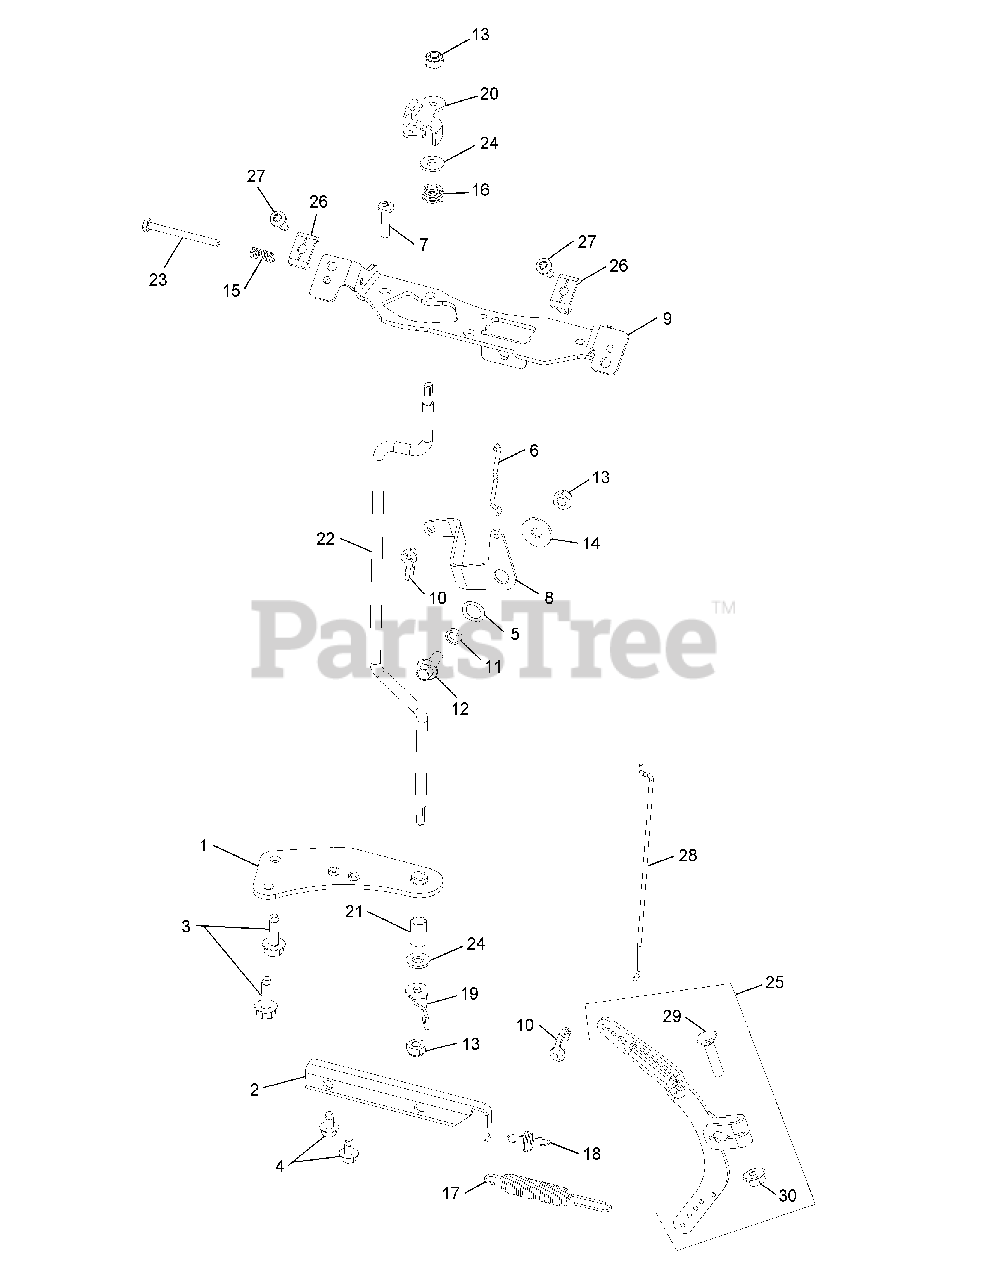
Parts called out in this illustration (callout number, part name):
1	Throttle Shaft Bracket
2	Governed Idle Bracket
3	Thread Forming Screw
4	Thread Forming Screw
5	Spring Washer, 3/8
6	Choke Linkage
7	Screw, 11-16 x 3/4
9	Control Bracket
10	Throttle Linkage Bushing
12	Flange Screw, M6 x 1.0 x 16
13	Lock Nut, M6 x 1.0
14	Flat Washer, 1/4
15	Speed Control Spring
16	Throttle Shaft Spring
17	Governor Spring
18	Governed Idle Spring
19	Throttle Control Lever
20	Throttle Control Lever
22	Control Shaft
23	Hex Head Screw
24	Flat Washer, 1/4
25	Governor Lever
27	Thread Forming Screw
28	Throttle Linkage
29	Bolt, M6 x 1.0 x 25
30	Flange Nut, M6 x 1.0
